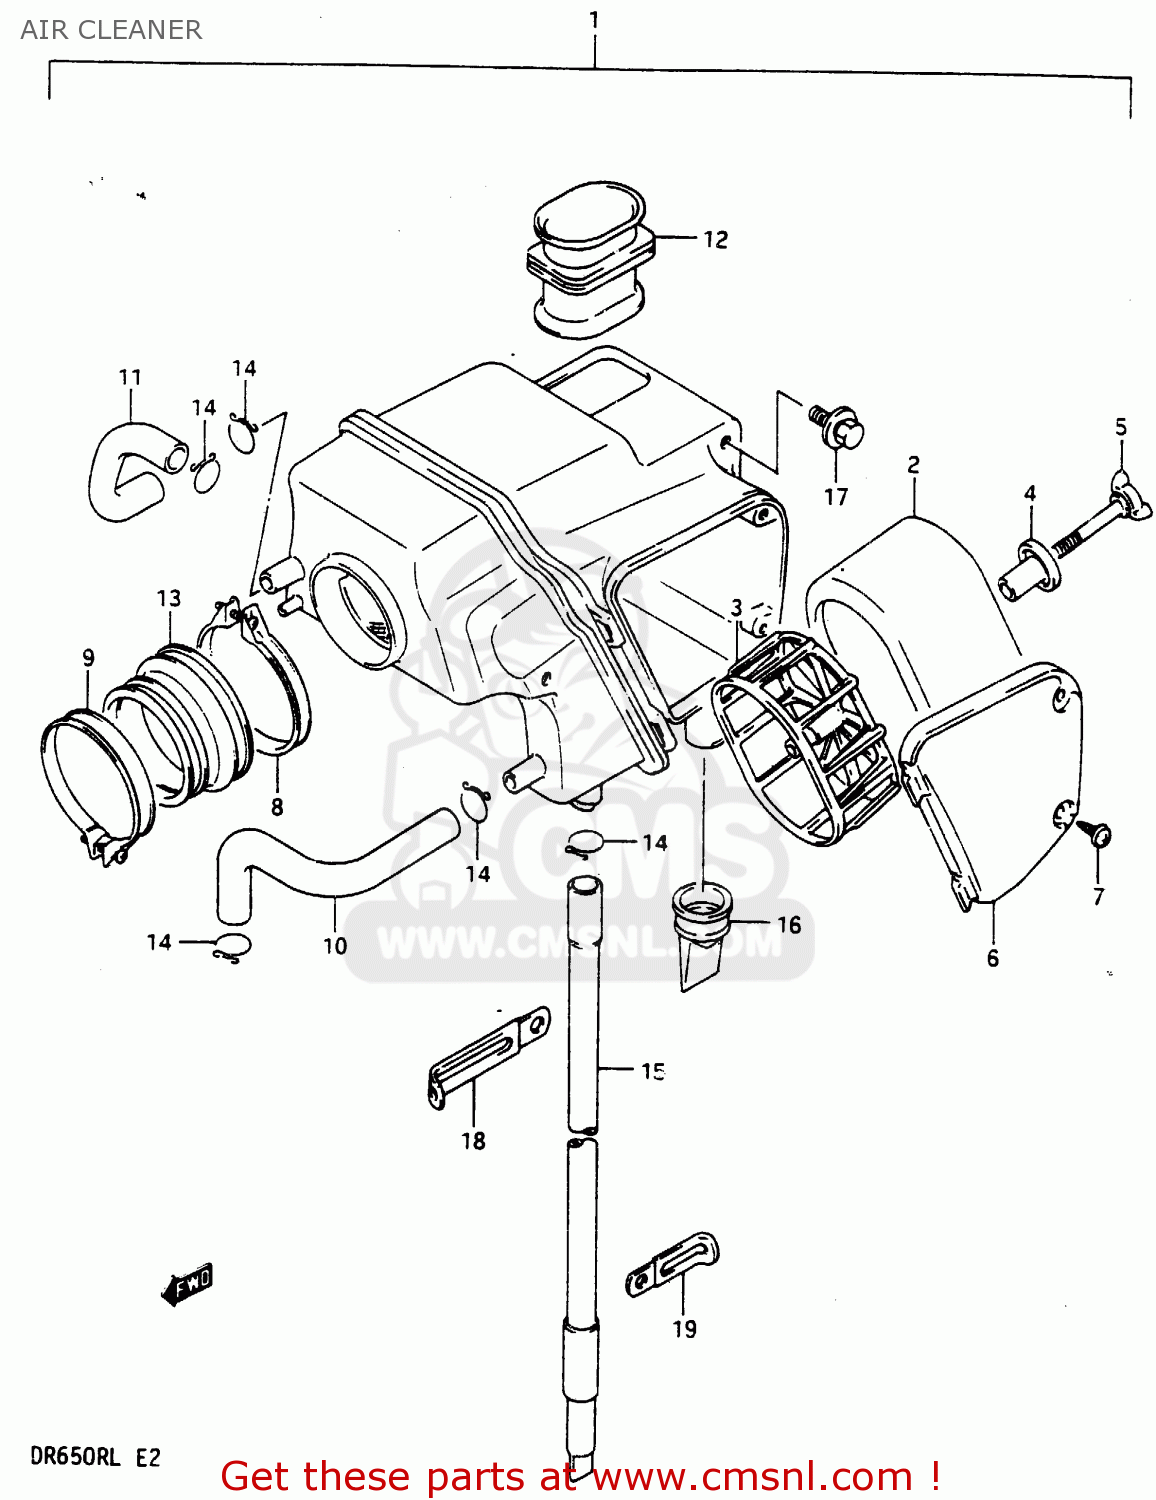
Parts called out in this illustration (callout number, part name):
1	CLEANER ASSY, AIR
2	FILTER
3	HOLDER,FILTER
4	SPACER
5	BOLT,WING
6	CAP,AIR CLEANER
7	SCREW
8	CLAMP
9	CLAMP
10	TUBE,BREATHER
11	TUBE,CONNECTING
12	TUBE,INLET
13	TUBE,OUTLET
14	CLIP
15	DRAIN TUBE
16	CAP,DRAIN
17	BOLT(6X14)
18	CLAMP
19	CLAMP L:35
